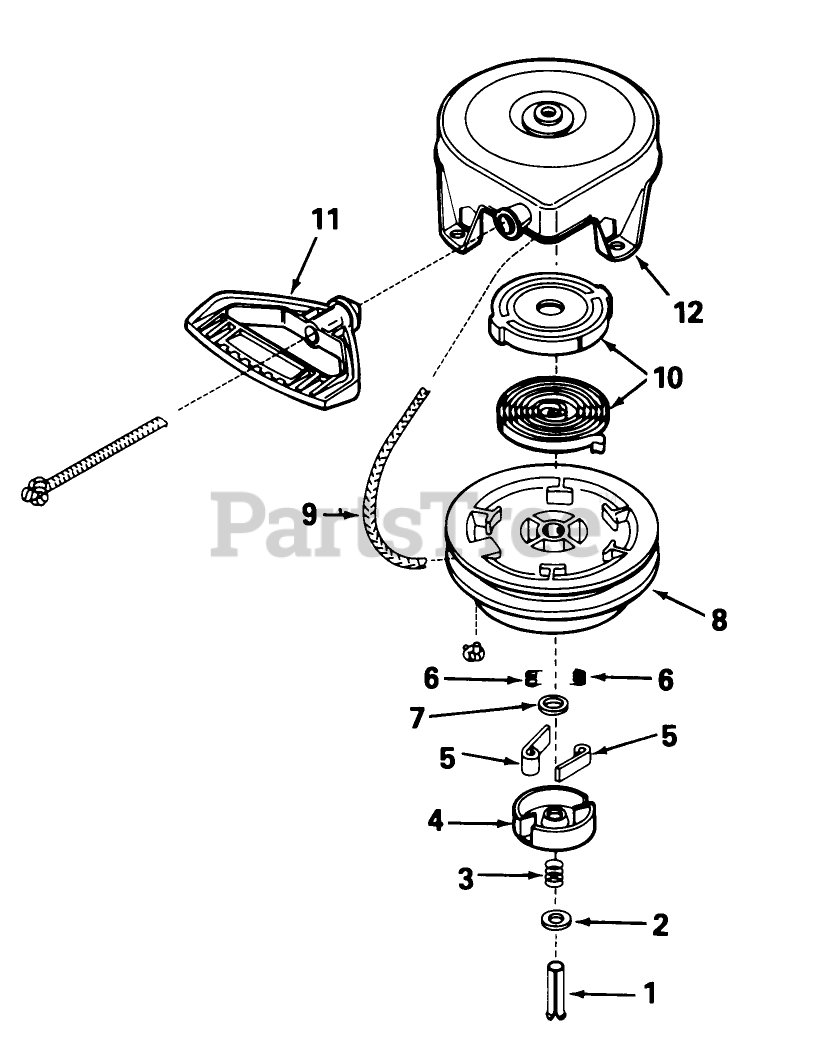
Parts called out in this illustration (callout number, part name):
1	Pin Spring
2	Washer
3	Brake Spring
4	Retainer
5	Dog-Starter
6	Spring-Dog
7	Washer
8	Pulley
9	Rope-Starter
10	Spring Keeper Assy.
11	Handle-Starter, Mitten Grip
12	Housing Assy., Starter
